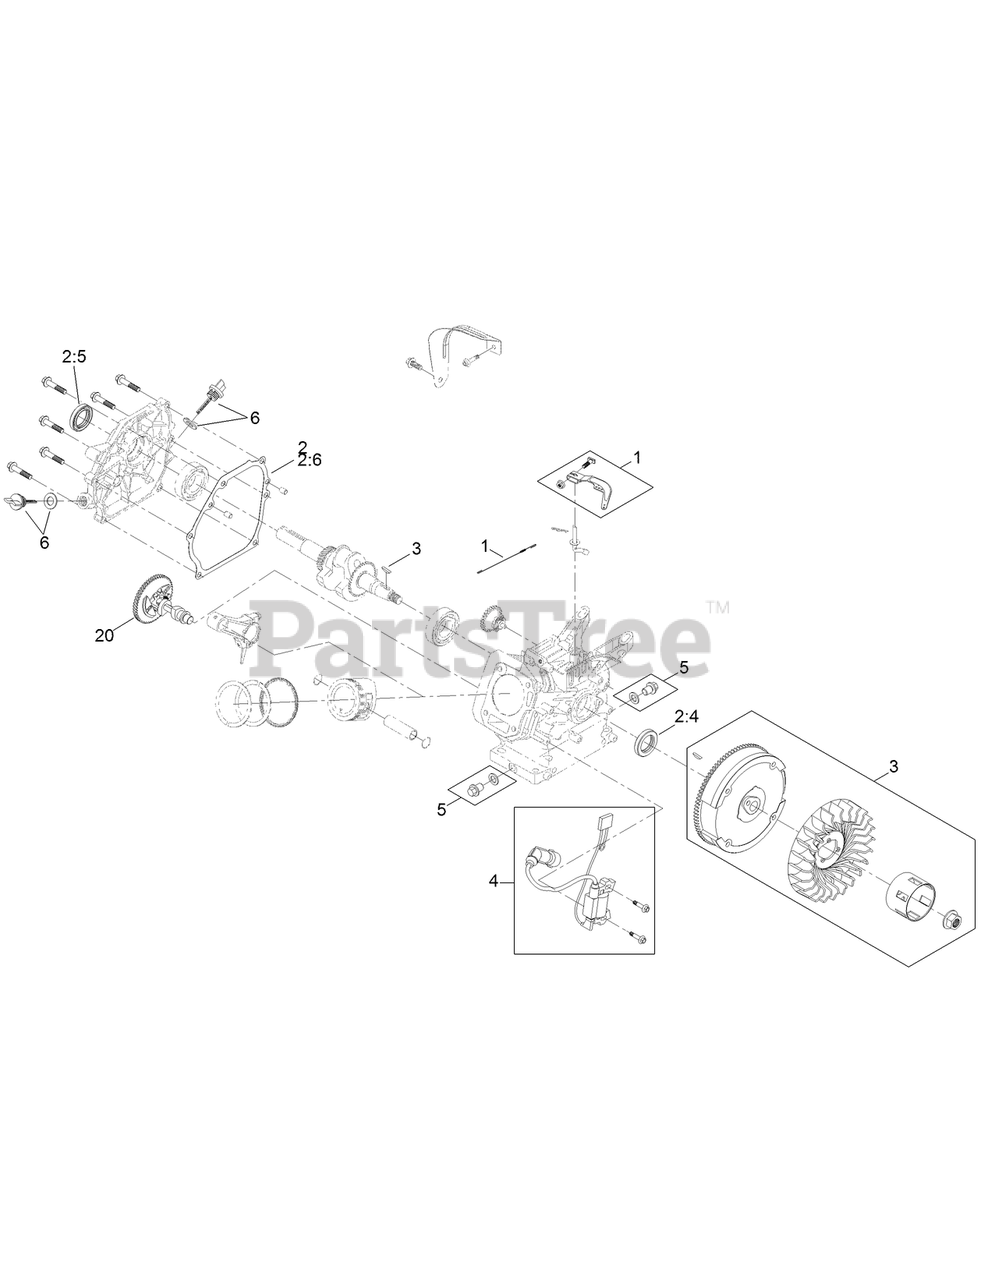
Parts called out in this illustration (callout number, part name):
1	GOVERNOR KIT
2	GASKET AND SEAL KIT
2:2	Gasket-Exhaust
2:3	GASKET-HEAD, CYLINDER
2:4	Loose Parts Package
2:5	Loose Parts Package
2:6	GASKET-COVER, CRANKCASE
2:7	GASKET-CARBURETOR
2:8	GASKET-CARBURETOR
2:9	GASKET-CARBURETOR
3	RECOIL FLYWHEEL KIT
5	DRAIN PLUG KIT
6	DIPSTICK AND O-RING KIT
20	CAMSHAFT
